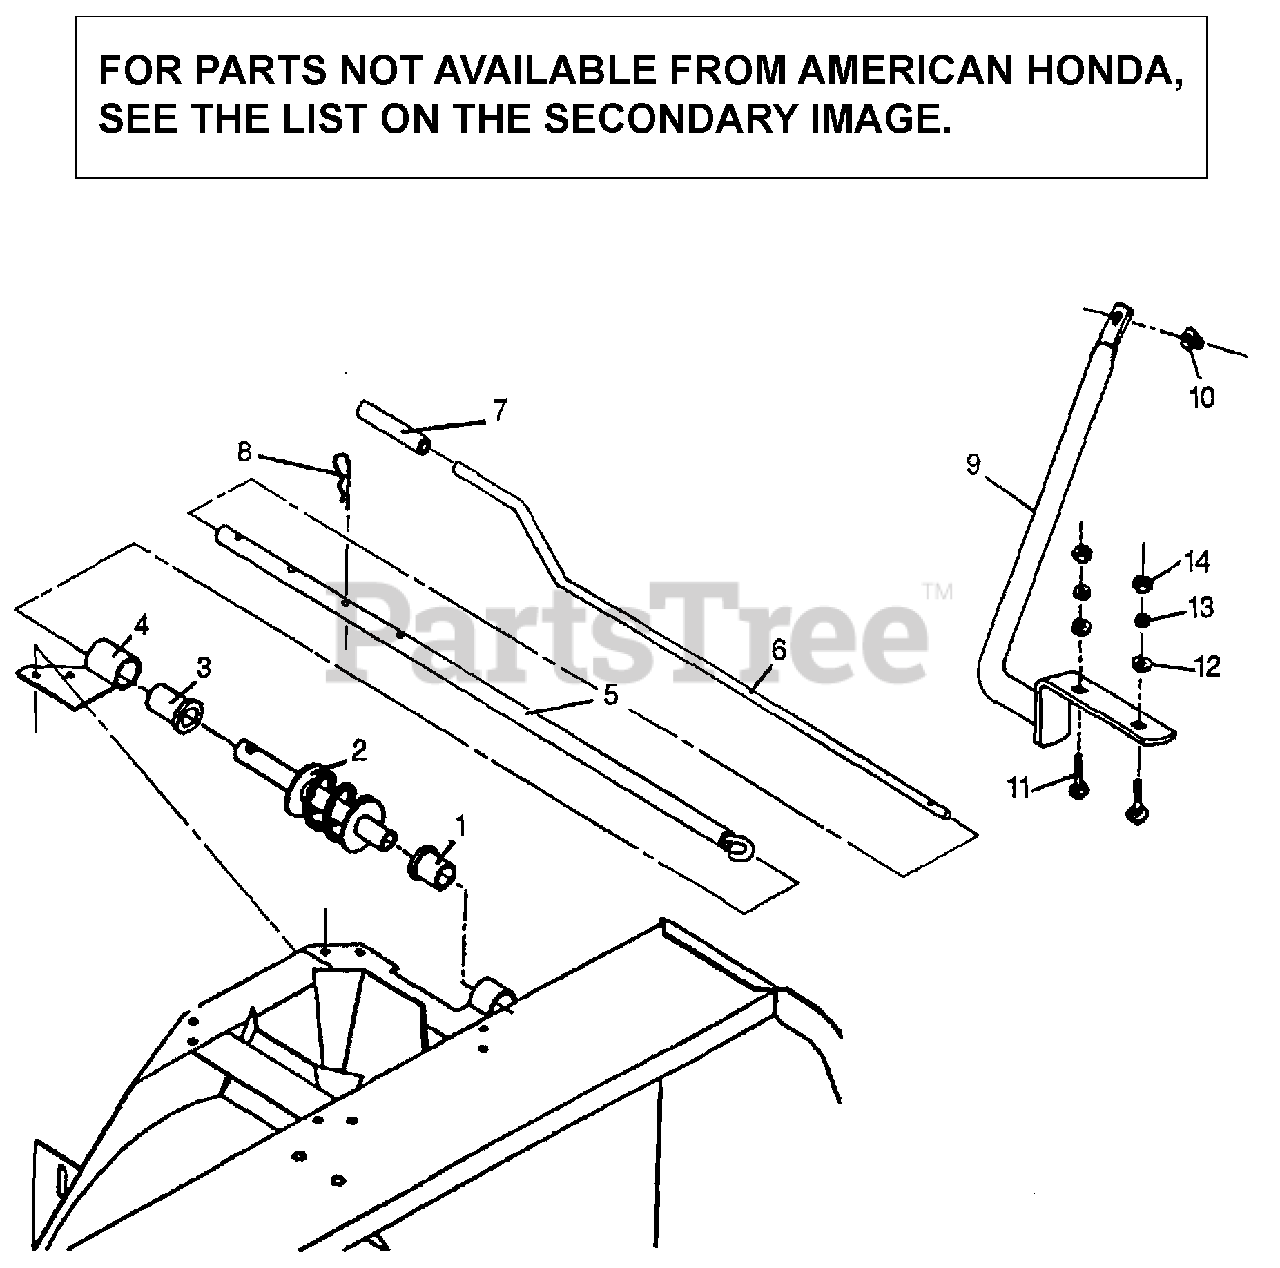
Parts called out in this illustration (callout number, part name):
1	BUSHING, PLASTIC (1-5/16")
2	WORM, ROTATION CLOCKWISE
3	BUSHING, PLASTIC (1-11/16")
4	SUPPORT, ROTATION WORM
5	TUBE, ROTATION (UPPER)
7	GRIP
9	SUPPORT, ROTATION HANDLE (NOT AVAILABLE)
10	GROMMET, PLASTIC
